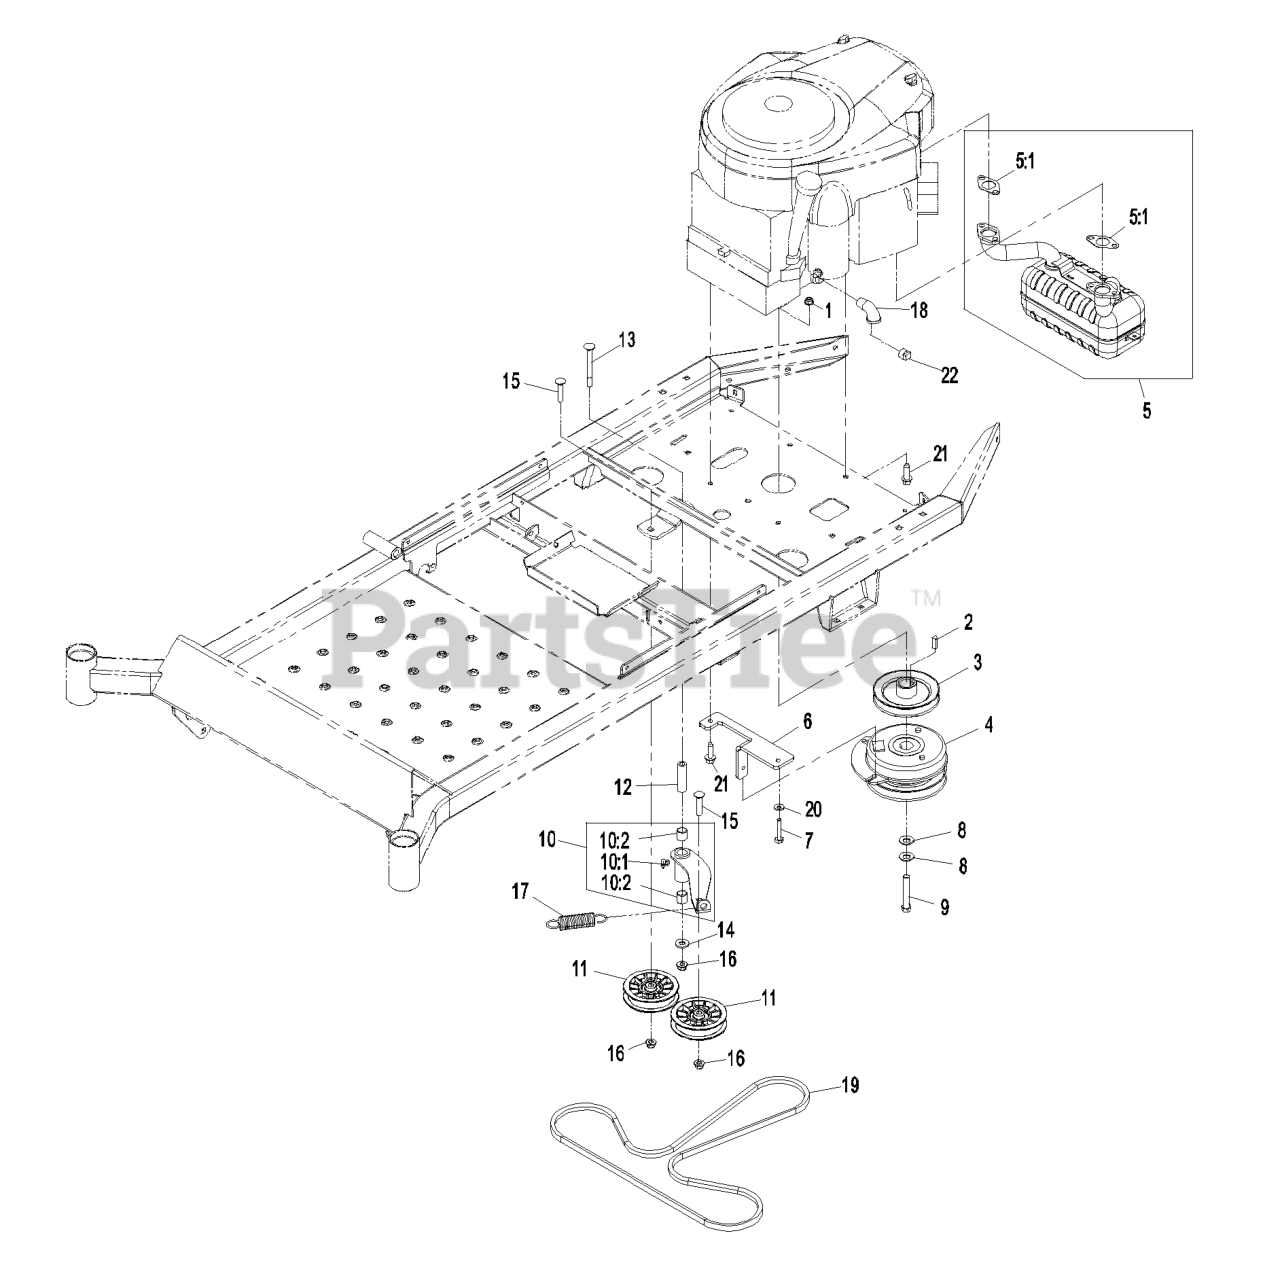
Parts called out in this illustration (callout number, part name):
1	NUT-HF, NI
3	SHEAVE-SPLIT STEEL
4	CLUTCH-ELECTRIC
5	MUFFLER ASM
5:1	GASKET-EXHAUST
6	ANCHOR-CLUTCH
7	SCREW-HH
8	WASHER-SPRING
9	SCREW-HH
10	IDLER ARM ASM
10:1	FITTING-GREASE, 90 DEG
10:2	SLEEVE-BEARING
11	PULLEY-IDLER, FLAT
12	BUSHING-PIVOT, IDLER
13	SCREW-CARR
14	WASHER-FLAT
15	SCREW-CARR
16	NUT-HF, NI
17	SPRING-EXTENSION
18	ELBOW-90 DEG
19	V-BELT
20	WASHER-SPRING
21	SCREW-THD
22	PLUG-PIPE, SQH
